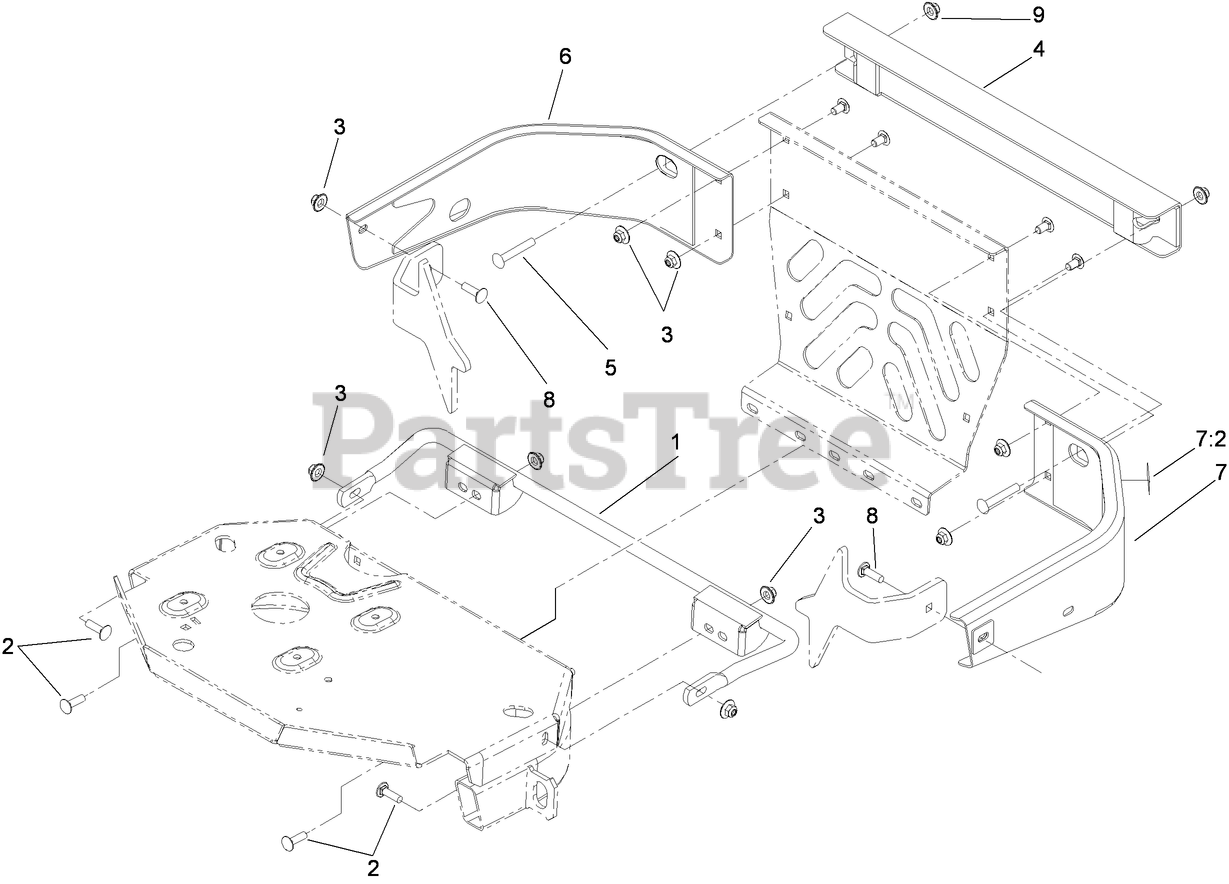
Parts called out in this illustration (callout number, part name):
1	MOUNT-BAGGER, LOWER
2	SCREW-CARR
3	NUT-FLANGE, NI
4	MOUNT-BAGGER, UPPER
5	SCREW-CARR
6	BUMPER-RH
7	LH BUMPER ASM
7:2	DECAL-CAUTION
8	SCREW-CARR
9	NUT-LOCK
